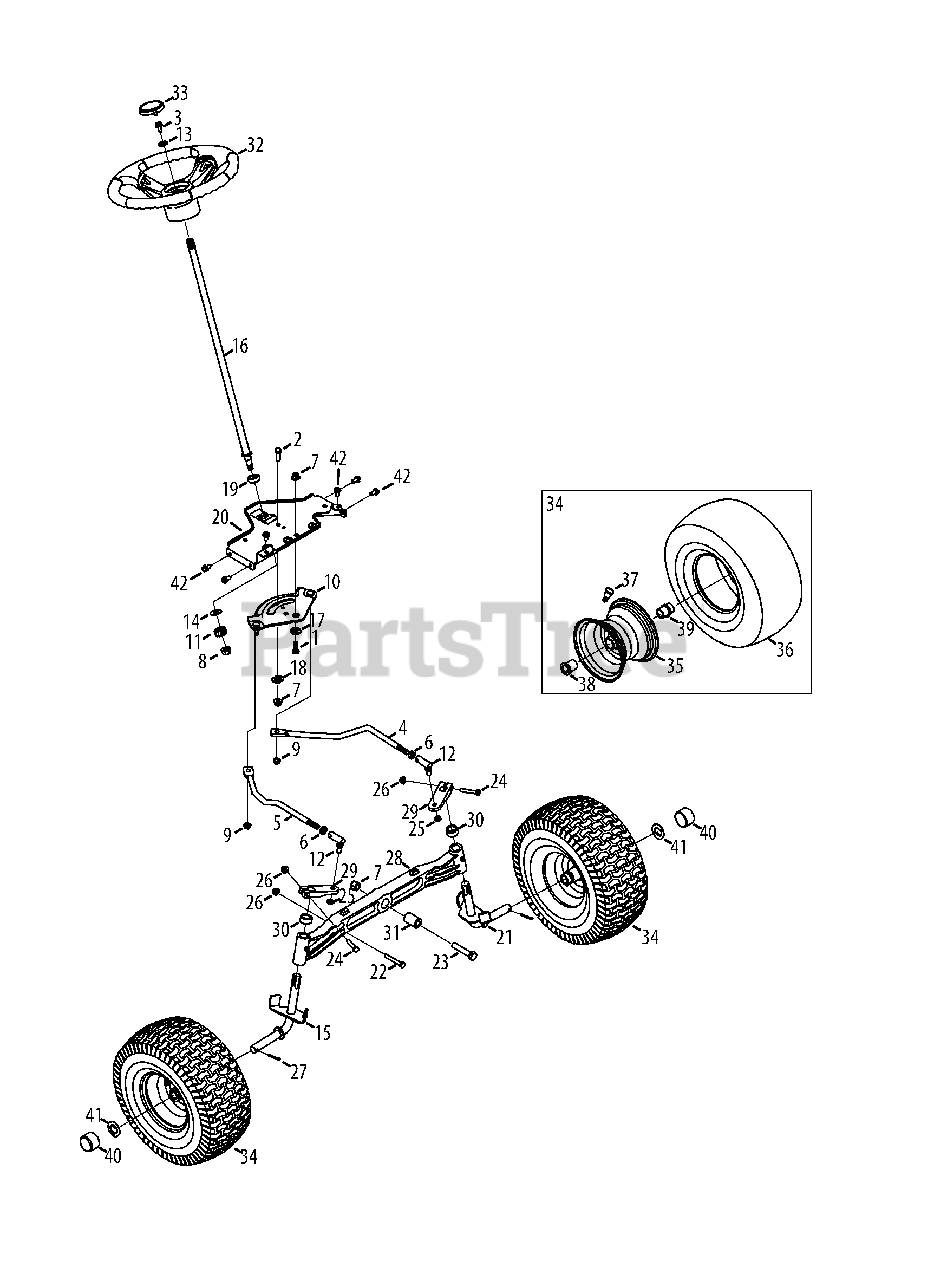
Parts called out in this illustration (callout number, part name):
1	Hex Head Screw, 3/8-16:1.00
2	Hex Head Screw, 3/8-16:1.00
3	Hex Head Screw, 5/16-18:1.00
4	LH Drag Link
5	RH Drag Link
6	Jam Nut, 7/16-20
7	Flangelock Nut, 3/8-16
8	Flangelock Nut, 7/16-20
9	Flangelock Nut, 5/16-18
10	Steering Gear
11	Steering Pinion Gear
12	Ball Joint, 7/16-20
13	Flat Washer, .406 x .875 x .105
14	Flat Washer, .51 x 1.12 x .06
15	RH Axle Assembly
16	Steering Shaft, .625 OD x 24.25 LG
17	Shoulder Spacer, .385 x 1.25 x .3025
18	Spacer, .38 x 1.375
19	Hex Flange Bearing 5/8 PM
20	Steering Support Bracket
21	LH Axle Assembly
22	Hex Head Screw, 5/16-18:2.25
23	Hex Head Screw, 3/8-16:2.50
24	Hex Head Screw, 5/16-18:1.75
25	Hexlock Nut, 3/8-24
26	Flangelock Nut, 5/16-18
27	Cotter Pin, 5/32:1.25
28	Pivot Bar Axle
29	Steering, Block
30	Spacer, .71 ID x .125 OD x .56LG
31	Spacer, .385 x 1.00 x 1.5075
32	Steering Wheel, Soft Grip
33	Cap, Troy-Bilt
34	Wheel Assembly
35	Rim Assembly
37	Tubeless Air Valve
38	Flange Bearing, .760 x 1.00 x 1.20LG
39	Flange Bearing, .760ID
40	Bumper Cap
41	Flat Washer, .781ID x 1.590OD
42	Screw, Self-tapping, 5/16-18, .750,
